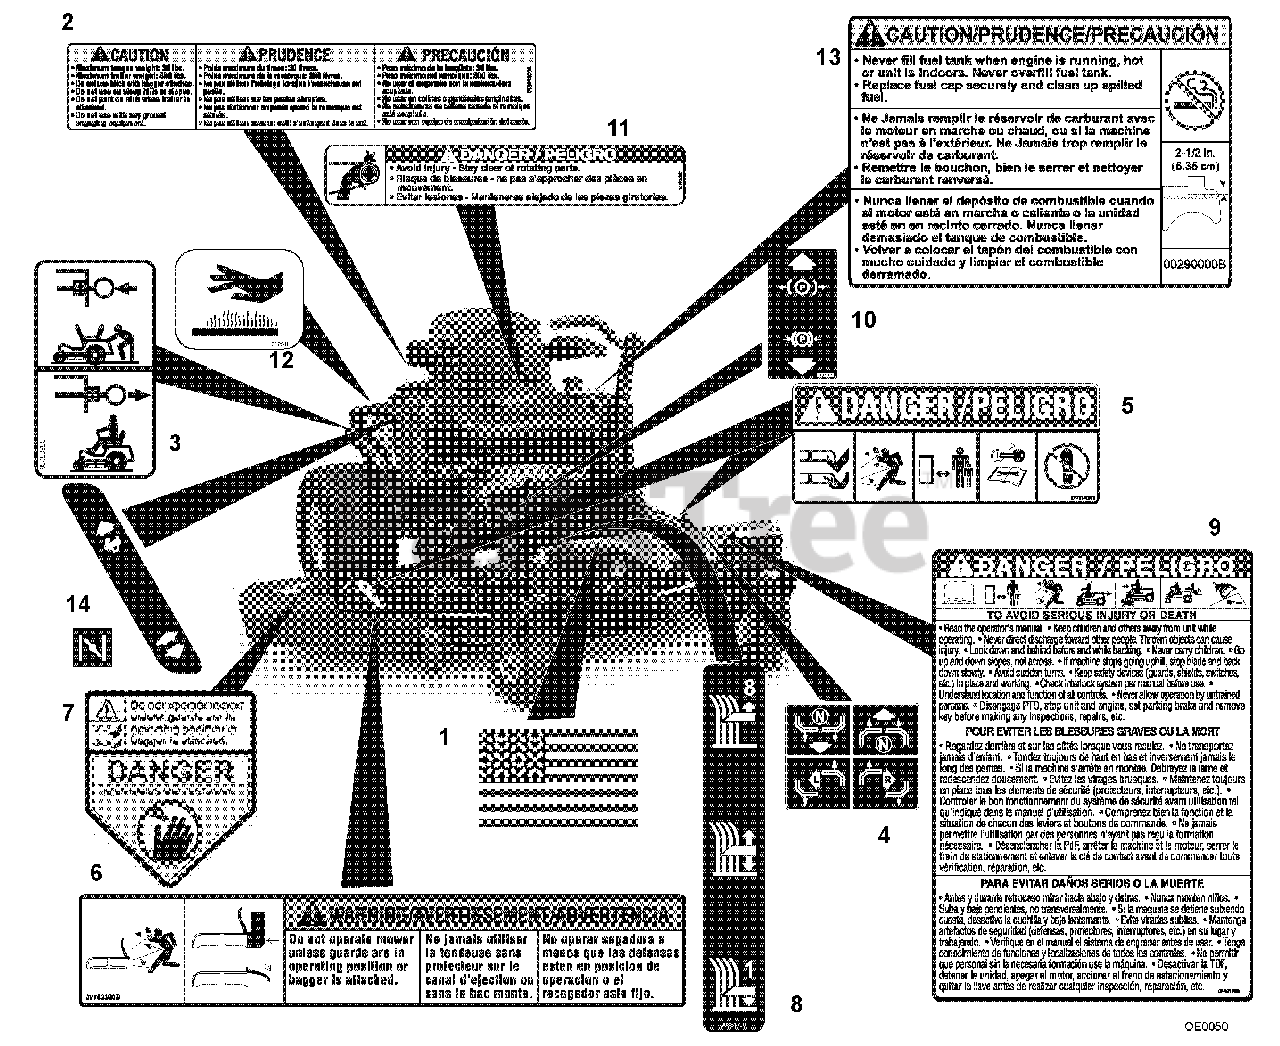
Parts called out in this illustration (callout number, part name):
1	DECAL, AMERICAN FLAG
2	DECAL, TRAILER HITCH
3	DECAL, TRANSMISSION DISCONNECT
4	DECAL, INSTRUCTIONAL-STEERING
5	DECAL, MOWER PAN DANGER
6	DECAL, WARNING
7	DECAL, CPSC DANGER
8	DECAL,CUT HEIGHT
9	DECAL, DANGER BILINGUAL
10	DECAL, PARKING BRAKE LEVER
11	DECAL- DANGER
12	DECAL, HOT SURFACE
13	DECAL,FUEL WARNING
14	DECAL, SPEED CONTROL
